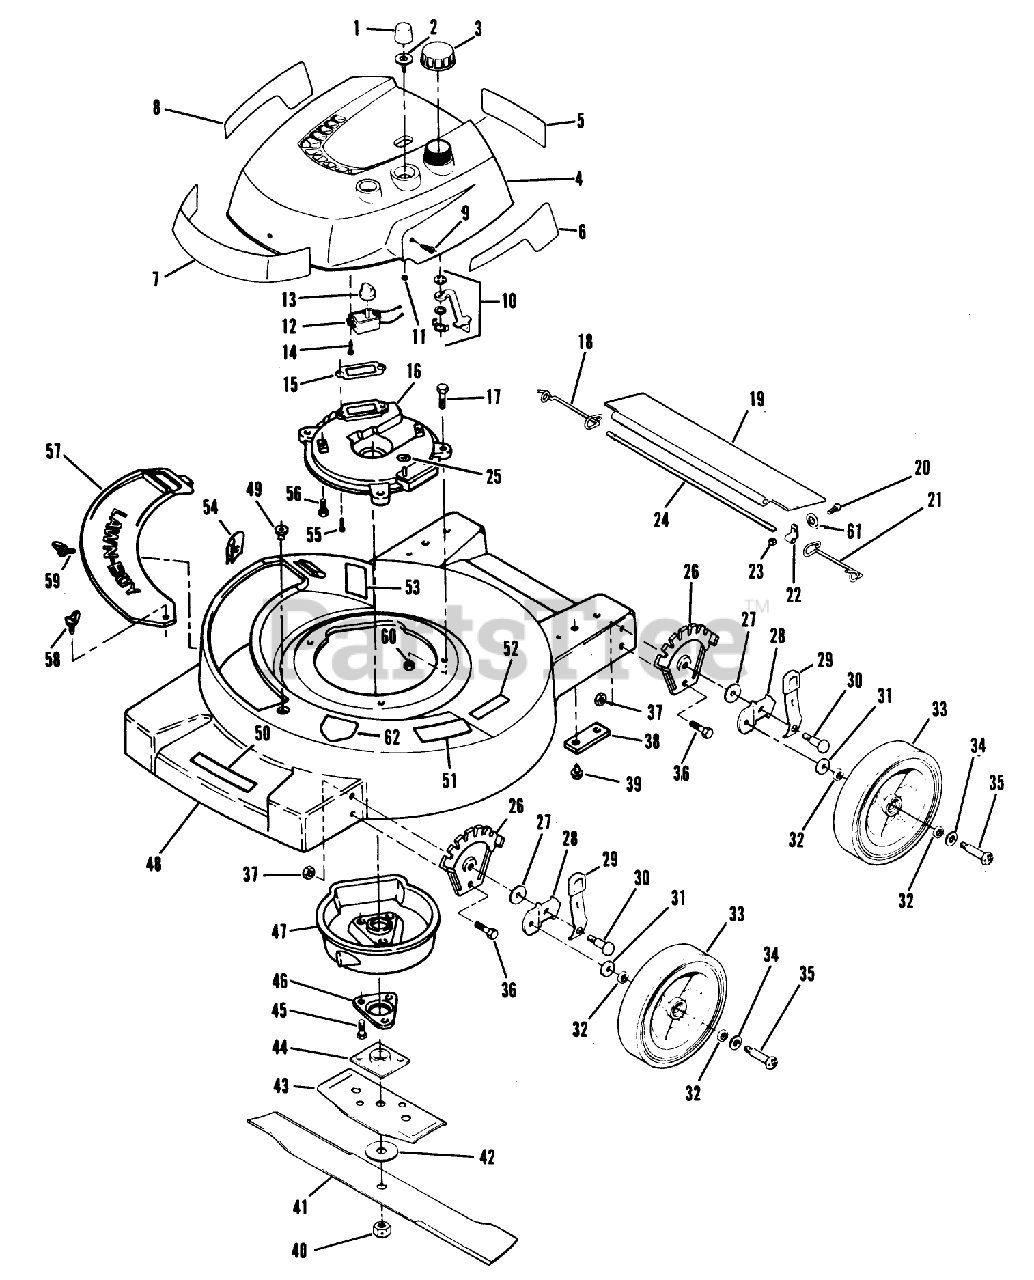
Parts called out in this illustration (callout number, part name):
9	SCREW S
11	LOCKNUT S
13	SWITCH KNOB
16	PLATE,MUFFLER F
18	SPRING;TRAILING SHIELD RH
21	SPRIG T/SHLD ASOC
22	CLAMP ROD KMC
23	LOCKNUT E
24	ROD 21" ADVANCE
31	WASHER WROUGHT
35	BOLT WHEEL
37	LOCKNUT
40	NUT-BLADE
44	PLATE AND COLLAR ASM
46	SUPPORT F
51	PAD FOOT
55	SCREW V
58	WING SCREW LAWRE
60	NUT-LOCK F
61	WASHER F
